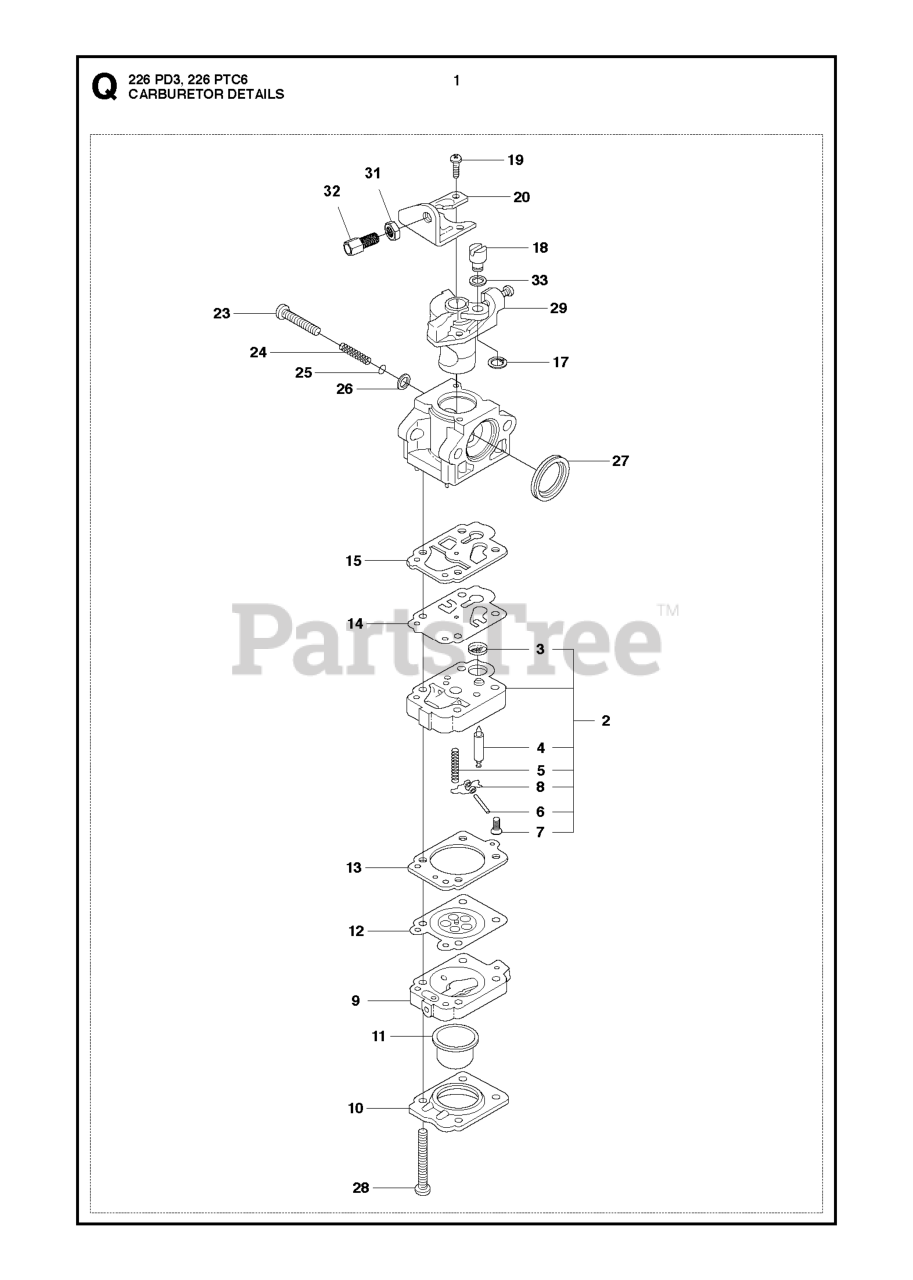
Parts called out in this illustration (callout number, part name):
1	CARBURETOR ASSEMBLY
3	SCREEN
4	VALVE INLET
24	SPRING
27	RING PACKING
31	NUT
32	ADJUSTER
